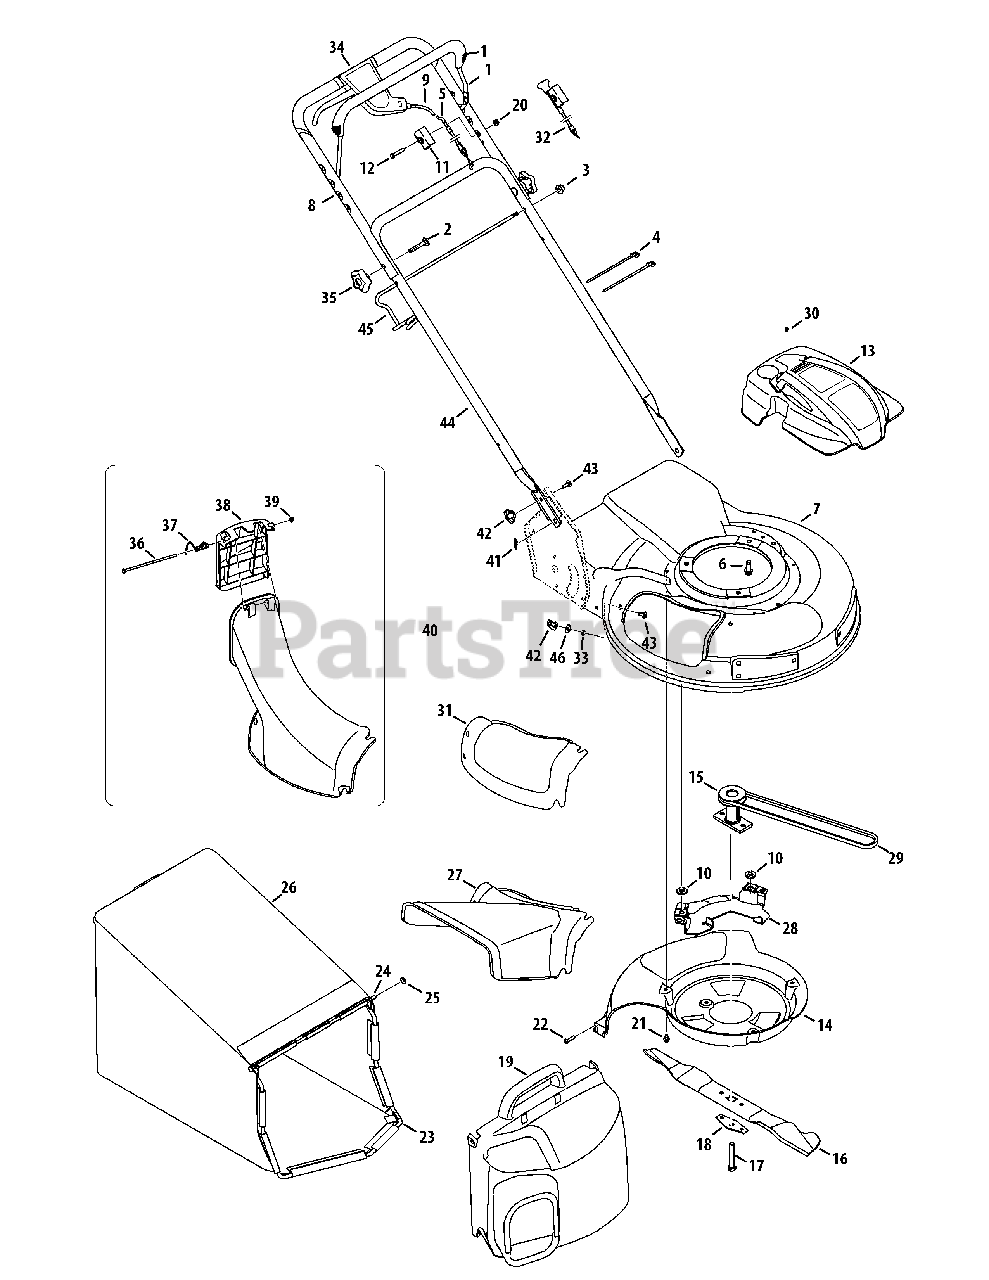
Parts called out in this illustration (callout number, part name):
1	Blade Control Assembly
2	Carriage Bolt 5/16-18 x 2
3	Flange Lock Nut, 5/16-18
4	Cable Tie
5	Control Cable
5	Control Cable - Kohler Engine
6	TT Screw, 3/8-16 x 1.00
9	Drive Cable
10	Washer, Flat, .407 x .812 x .135
11	Control Cable Mount
11	Control Cable Mount - Kohler
12	Screw, 1/4-20 x 1.50
13	Engine Shroud
14	Engine Baffle
15	Blade Adapter
15	Blade Adapter - Kohler
16	21-inch Mulching Blade
17	HH Cap Screw, 3/8-24 x 2.50
18	Bell Blade Spacer
19	Grass Bag Cover Assembly
20	Flange Lock Nut 1/4-20
21	TT Screw 1/4-20 x .375
22	HL Screw 1/4-15 x .75
23	Grass Bag Frame
24	Grass Bag Pivot Rod
25	Cap Speed Nut
26	Grass Bag Assembly
27	Side Discharge Chute
28	Belt Keeper
30	Screw, #12-16 x 1.00
31	Mulch Cover
32	Choke Cable
34	Drive Control Assembly
36	Chute Door Pivot Rod
37	Torsion Spring
38	Top Discharge Door Chute
40	Top Discharge Chute Assembly
41	Cotter Pin
43	Carriage Screw 1/4-20 x .75
45	Grass Bag Support Rod
46	Flat Washer, .260 x .720 x .060
